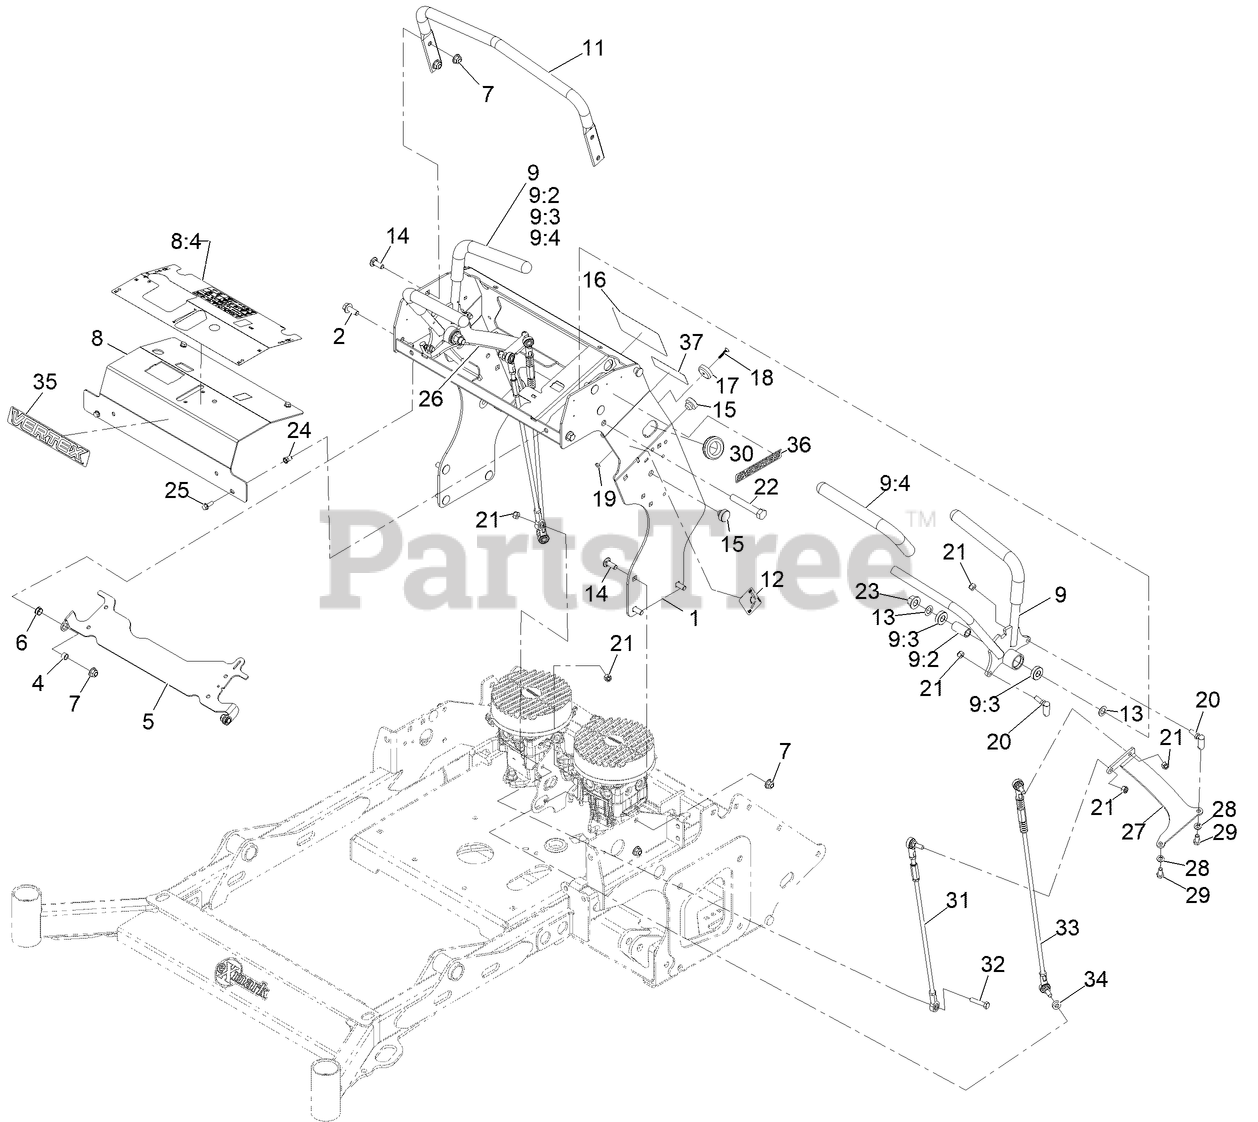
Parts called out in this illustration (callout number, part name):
1	ASM-Tower [red]
2	SCREW-HHF 3/8-16 X 1
4	SPACER-BRAKE PIVOT
5	Spacer-Brake Pivot
6	BUSHING,SNAP
7	NUT-HF, NI
8	PANEL-CONTROL W/ DECAL
8:4	DECAL-CONTROL PANEL NON-EFI
9	ASM-CTRL LEVER
9:3	BEARING-WHEEL
9:4	GRIP-HANDLE, CONTROL
11	BAR-REFERENCE
12	DECAL-PARK BRAKE, CE
14	SCREW-CARR
15	BUMPER-RUBBER
16	DECAL-SERVICE AID
17	MAGNET-RARE EARTH THIGH PAD
18	SCREW FLAT HD #10-24X1.00
19	NUT-LOCK
20	BALLJOINT-RH (W/GROMMET)
21	NUT-LOCK
22	SCREW-HH
23	Nut-Lock 1/2-13
24	Nut-Clinch, Hex
25	SCREW-HHF
26	BRACKET-LINK CTRL LH
27	BRACKET-LINK CTRL RH
28	WASHER-LOCK
29	SCREW-HH
30	GROMMET
31	ASM-MOTION CONTROL SHORT
32	SCREW-HH
33	ASM-MOTION CONTROL LONG
35	DECAL-VERTEX LOGO
36	Decal-S-Series
37	DECAL-FUSE
